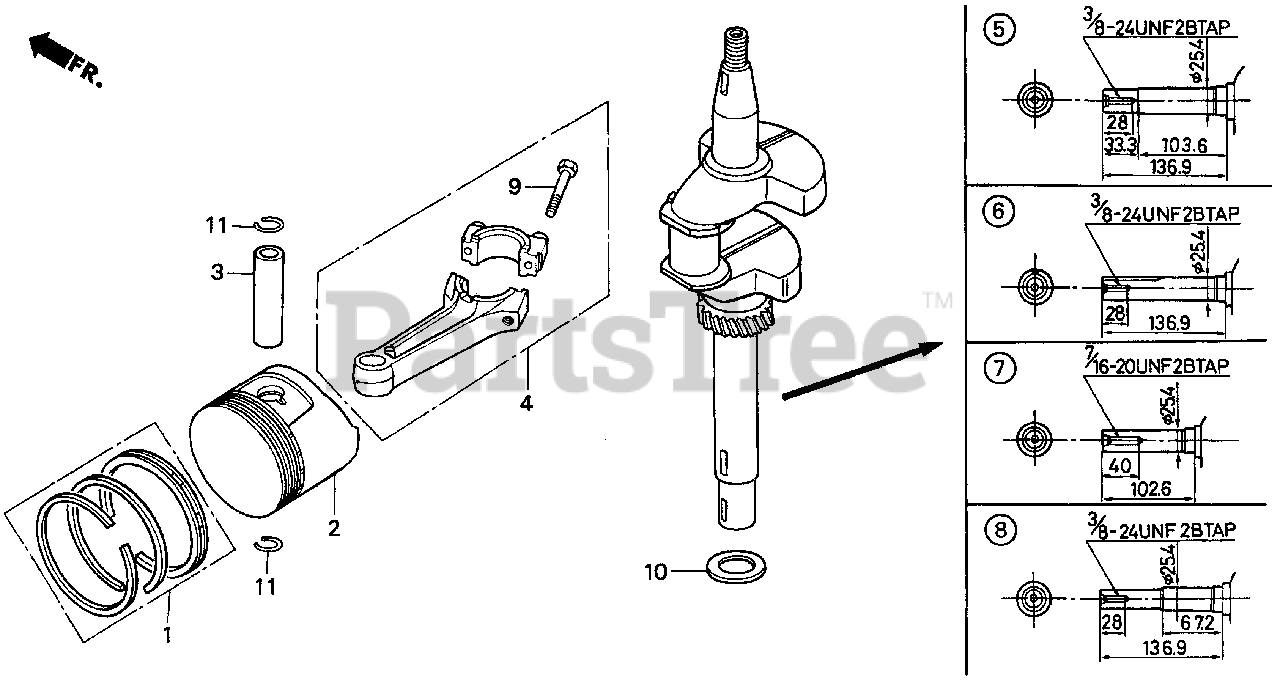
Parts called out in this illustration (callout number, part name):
1	RING SET, PISTON (STD)
1	RING SET, PISTON (OS 0.25)
1	RING SET, PISTON (OS 0.50)
1	RING SET, PISTON (0.75)
2	PISTON (STD)
2	PISTON (OS 0.25)
2	PISTON (OS 0.50)
2	PISTON (0.75)
3	PIN, PISTON
4	ROD ASSY., CONNECTING
4	ROD ASSY., CONNECTING (U.S. 0.25)
5	CRANKSHAFT (N1 TYPE)
9	BOLT, CONNECTING ROD
10	WASHER, THRUST (25.6MM)
11	CLIP, PISTON PIN (18MM)
